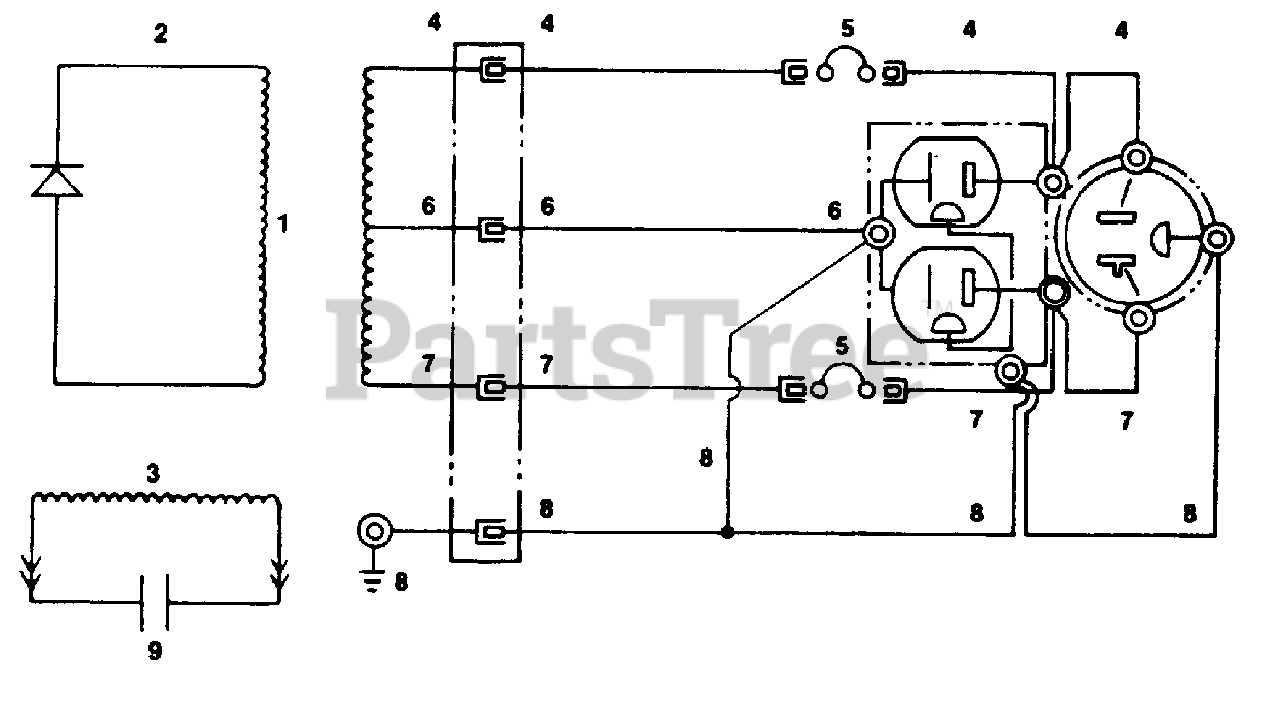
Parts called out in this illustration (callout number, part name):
1	Main Coil
2	Field Coil
3	Coil Condenser
4	Red
5	Circuit Protector
6	White
7	Blue
8	Ground
9	Condenser
